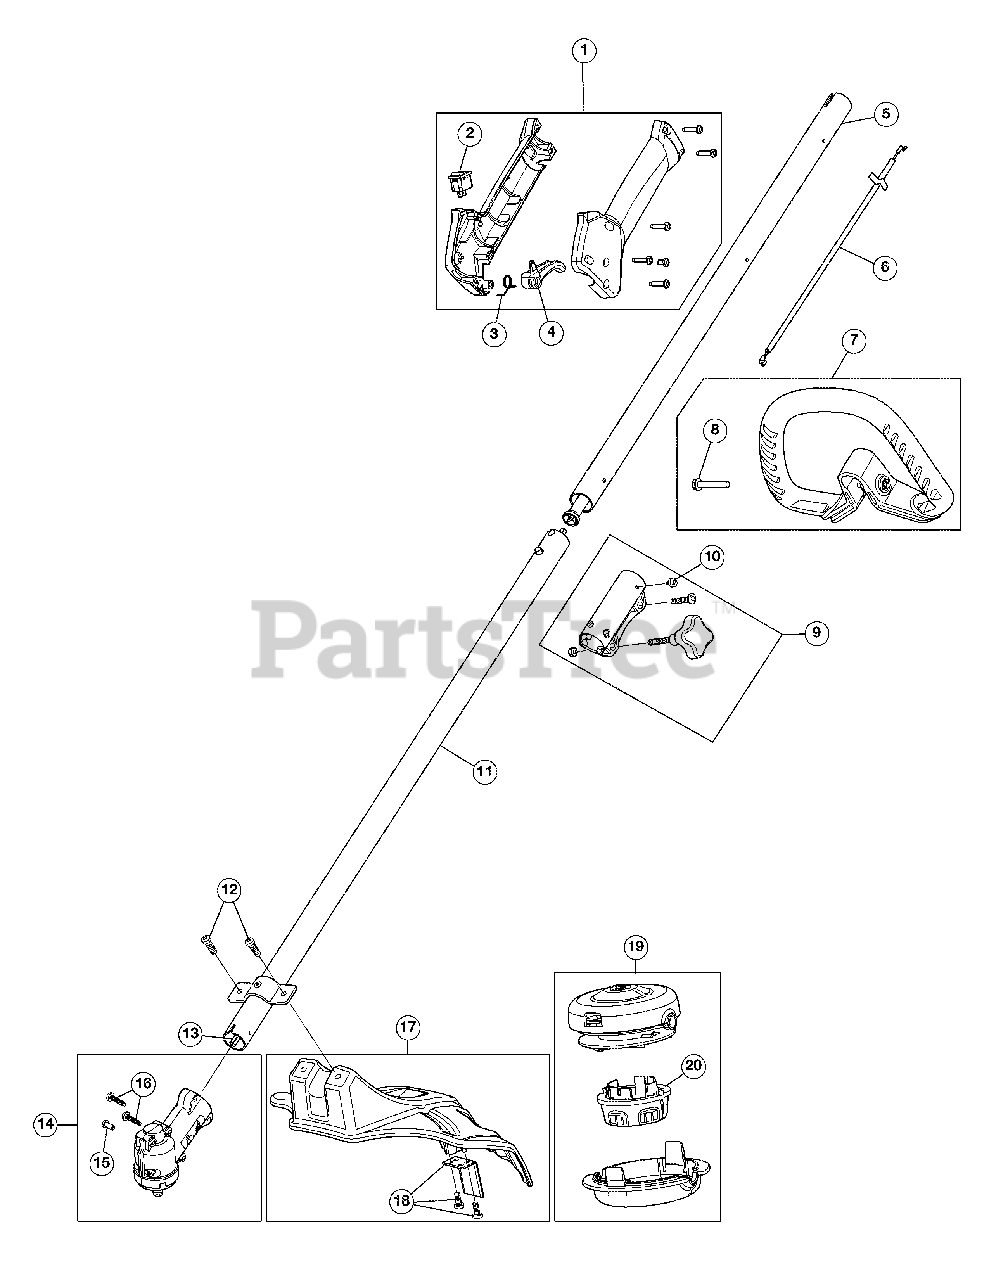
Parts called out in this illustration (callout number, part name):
1	Throttle Housing Assembly (Incl. 2 - 4)
2	Trigger Switch Assembly
3	Throttle Trigger Spring
4	Throttle Trigger
5	Upper Drive Shaft Assembly
6	Throttle Cable Assembly
7	D-Handle Assembly (Incl. 8)
9	Split Boom Coupler (Incl. 10)
10	Coupler Anti-Rotation Screw
11	Lower Drive Shaft Housing
12	Shield Mounting Screws
13	Lower Flexible Drive Shaft
14	Gearbox Assembly (Incl. 15 and 16)
15	Gearbox Anti-Rotation Screw
16	Gearbox Mounting Hardware
17	Shield Assembly (Incl. 18)
18	Blade Assembly
19	Cutting Head Assembly (Incl. 19)
20	Bump Knob
